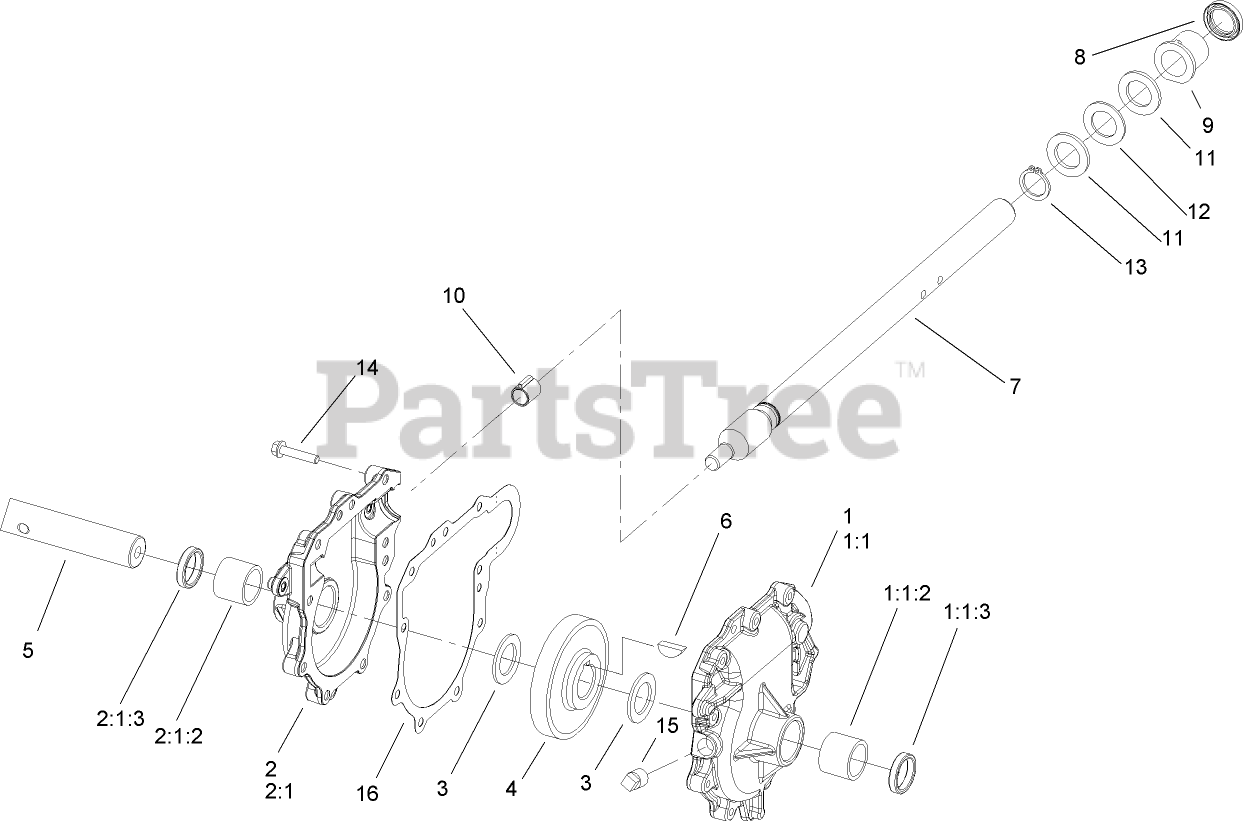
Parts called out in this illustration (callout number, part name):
1	LH AUGER GEARCASE ASM
1:1	Gearcase-Auger, LH
1:1:2	BUSHING-SLEEVE
1:1:3	SEAL-OIL
2	RH AUGER GEARCASE ASM
2:1	Loose Parts Package
2:1:2	BUSHING-SLEEVE
2:1:3	SEAL-OIL
3	WASHER-THRUST
4	GEAR-HELICAL
5	SHAFT-AUGER
6	KEY-WOODRUFF
7	SHAFT-IMPELLER
8	SEAL-OIL
9	BUSHING-INPUT
10	BUSHING-WORM
11	WASHER-THRUST
12	BEARING-THRUST
13	RING-RETAINING, EXT
14	SCREW-HWHTF
15	PLUG-PIPE, SQH
16	GASKET-GEARCASE, AUGER
